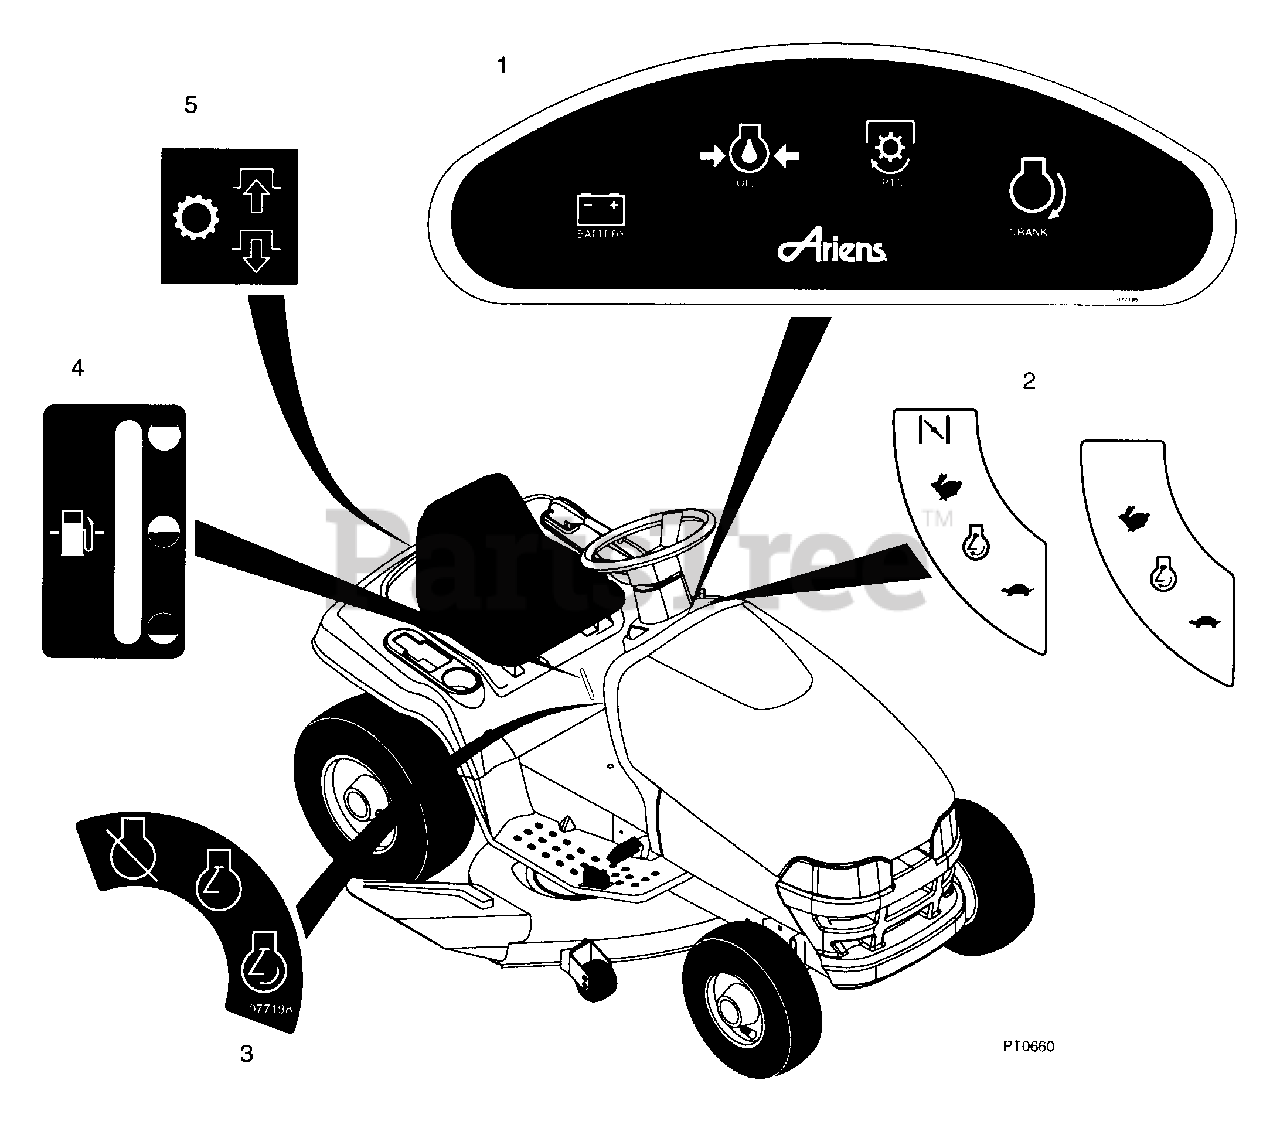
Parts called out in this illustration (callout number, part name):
1	DECAL- DASH W/ LIGHTS
2	DECAL- THROTTLE W/ CHOKE
2	DECAL- THROTTLE W/O CHOKE
3	DECAL - IGNITION
4	DECAL- FUEL LEVEL
5	DECAL-TRANS. DISCONNECT
